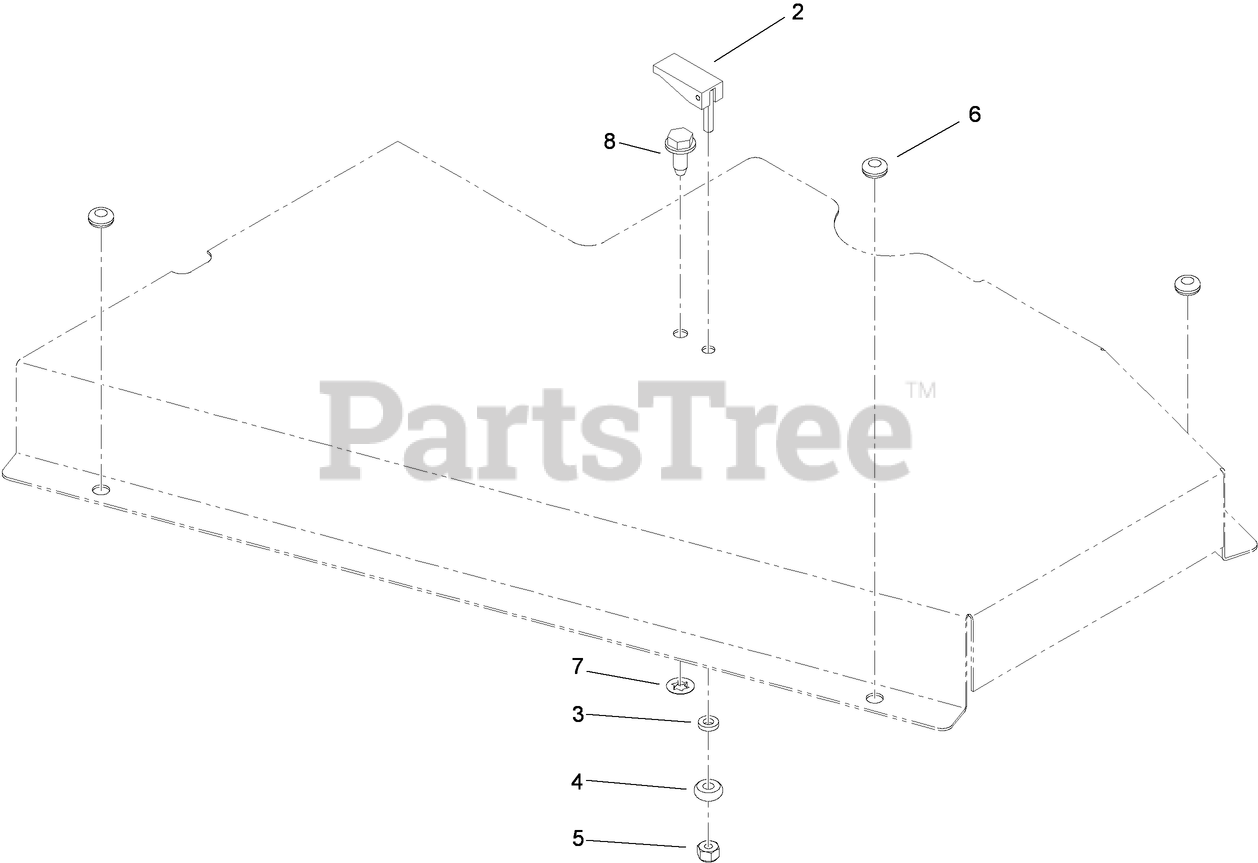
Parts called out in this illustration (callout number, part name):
2	GROMMET
3	HANDLE-LATCH, SWELL
4	WASHER
5	BUSHING-LATCH, SWELL
6	NUT-LOCK, HH
7	RING-RETAINING, BOLT
8	SCREW-HWHTF
